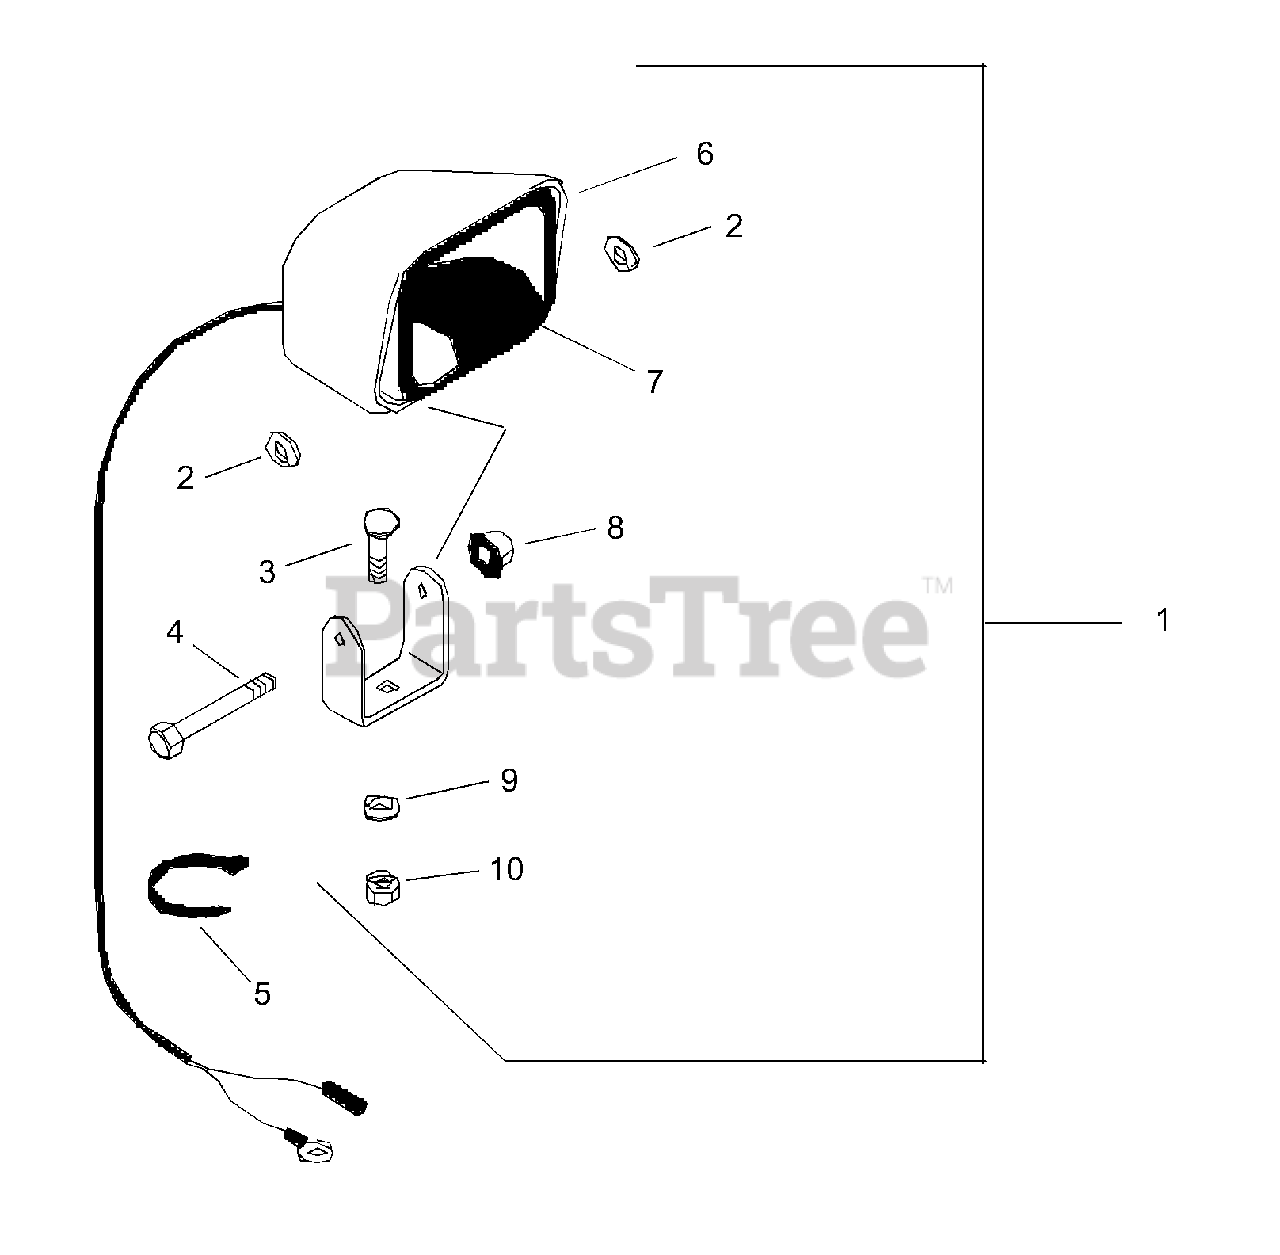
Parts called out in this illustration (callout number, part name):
1	HEADLIGHT
2	@WSHR-LK-EXT.326X.599X.031YWZC
3	@BLT-RDHDSQNK .31-18X1.00 G5YZ
4	@BLT-HEX .31-18X2.50 GR5 YWZC
5	CABLE TIE LG 5-1/2
6	LENSE-FLOOD
8	@NUT-SPNLK-FLG .312-18 YWZC
9	WSHR-LK .312X.097 HVY YWZC
10	@NUT-HEX .31-18 YWZC
